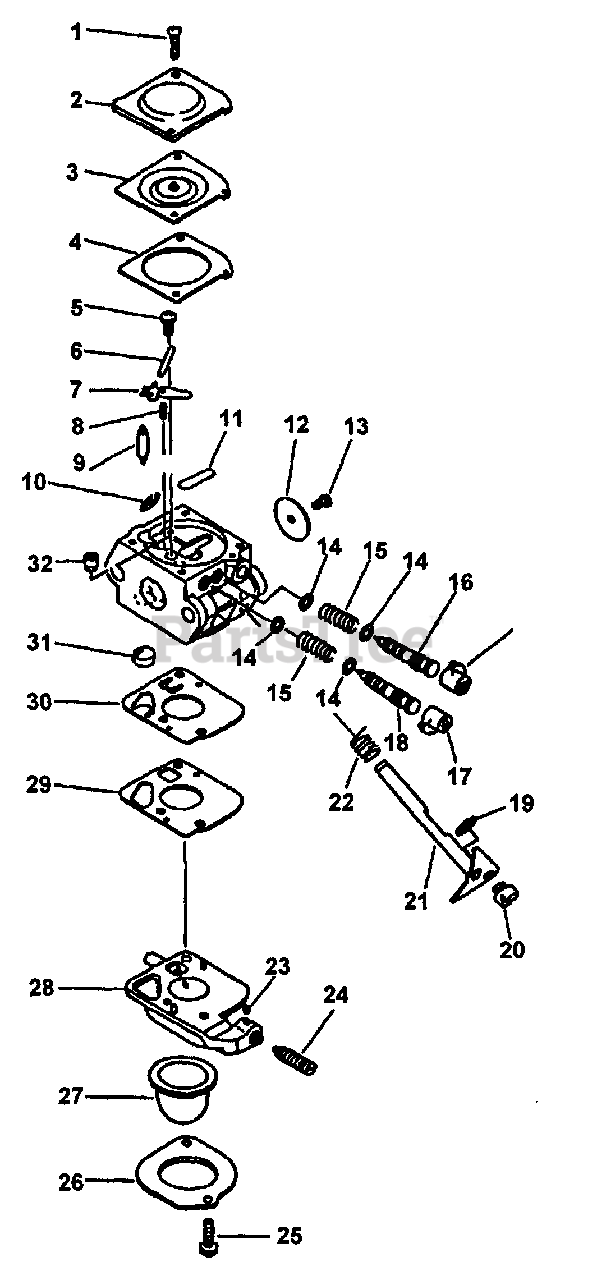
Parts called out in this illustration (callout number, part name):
2	COVER, METERING DIAPHRAGM
3	DIAPHRAGM, METERING
4	GASKET, METERING
6	PIN, METERING LEVER
7	LEVER, METERING
8	SPRING, METERING LEVER
9	VALVE, NEEDLE
11	PLUG, WELCH
12	VALVE, THROTTLE
15	SPRING, NEEDLE
16	NEEDLE, IDLE
17	NEEDLE, HIGH SPEED
18	CAP, LIMITER - RED
21	SHAFT, THROTTLE
22	SPRING, THROTTLE RETURN
23	PIECE, FRICTION
24	SCREW, IDLE ADJUST
26	RETAINER
27	BULB, PURGE
28	BODY ASSY, PURGE
31	STRAINER
32	NOZZLE, CHECK VALVE
